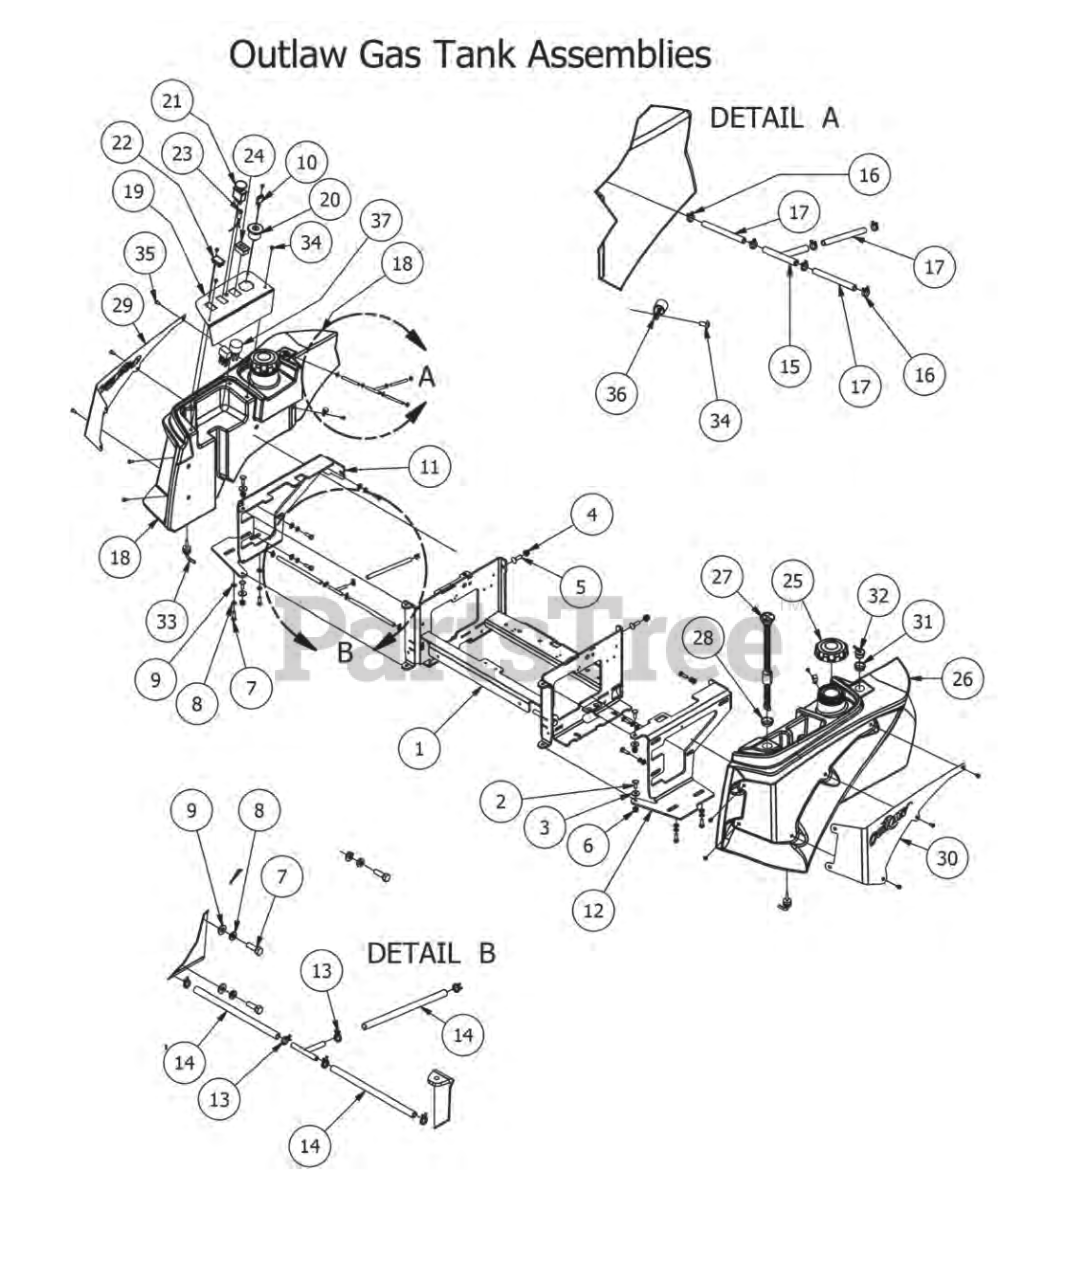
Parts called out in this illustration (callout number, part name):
1	2015 Outlaw Seat Bracket
2	5/16-18 x 1 Carriage Bolts Zinc
3	360 ID Plastic Washer
4	3/8" Nylock Flange Nut
5	3/8" x 1 1/4" Carriage Bolt
6	5/16-18 Nylon Insert Flange Nut Zinc Orange Nylon
7	5/16" x 1" Bolt
8	5/16" Lock Washer
9	5/16" Flat Washer
10	Ignition Key
11	Outlaw 2015 Tank Support (Right)
12	Outlaw 2015 Tank Support (Left)
13	1/4 fuel clamp
14	1/4" fuel line hose
15	fuel line T
16	3/16 vinyl clamp
17	1/4" vinyl tubing
18	Outlaw 2015 Fuel Tank (Right)
19	Analog Control Panel Outlaw
20	Ignition Switch
21	PTO Switch
22	Light Plug
24	Tachometer
25	Fuel Cap (Kelch)
26	Outlaw 2015 Fuel Tank (Left)
27	Fuel Gauge w/Grommet
28	Grommet for Fuel Gauge
29	Outlaw Tank Panel (Right)
30	Outlaw Tank Panel (Left)
31	ROV Grommet
32	Rollover Valve - Black
33	Fuel Tank Hose Nipple w/Filter
34	10-32 x 3/8" Button Socket Head Bolt
35	1/4" x 1/2" BS C/S 18-8 SS
36	3/8 Cable Clamp-Black Nylon
37	Wiring Harness
